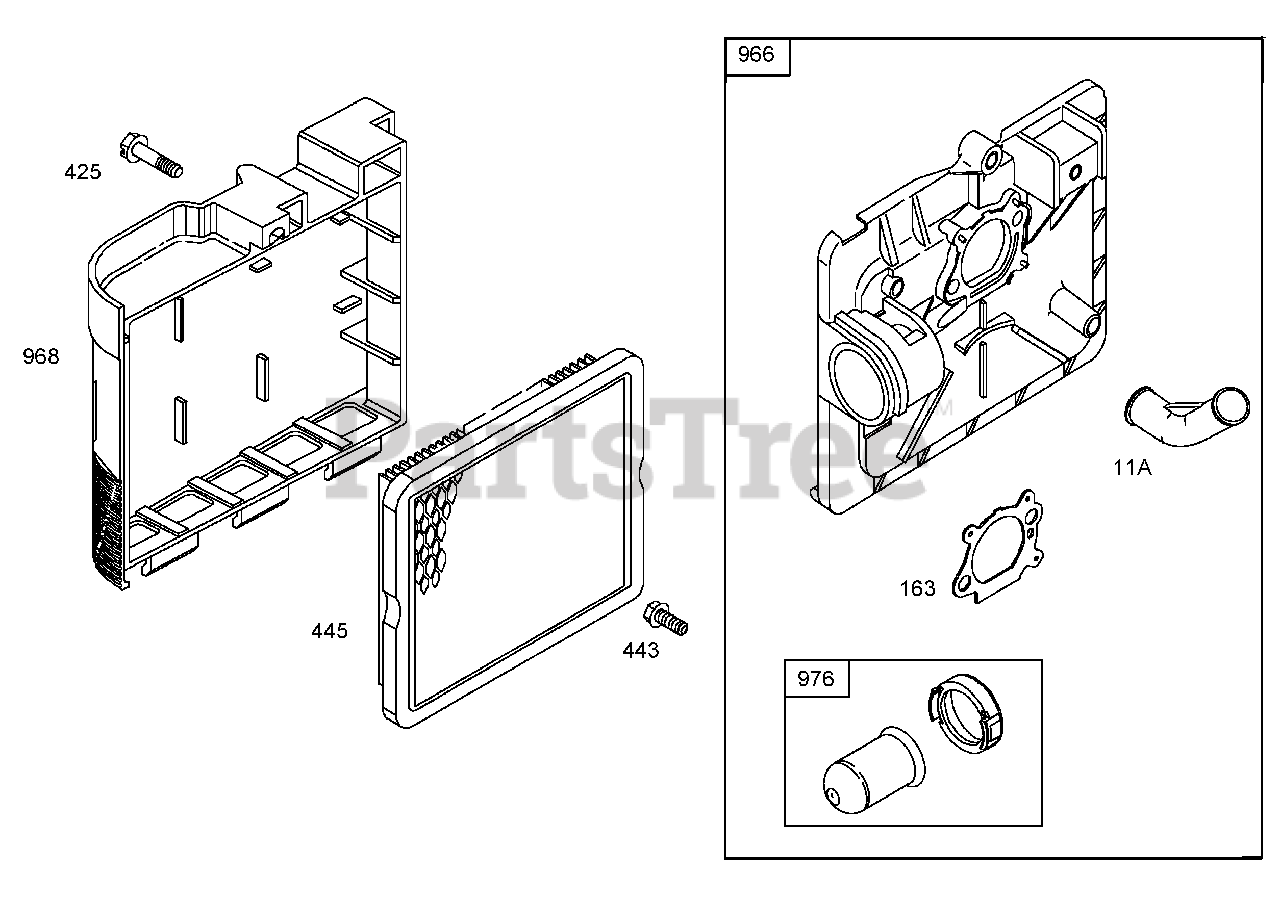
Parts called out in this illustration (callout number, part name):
11A	Bolt-Hex, Hollow (3/8-16 x 3/4)
163	GasketCleaner, Air
425	Screw
443	Screw (Air Cleaner Primer Base)
445	FilterCartridge, Air Cleaner
966	BasePrimer, Air Cleaner
968	CoverCleaner, Air
976	PrimerCarburetor
